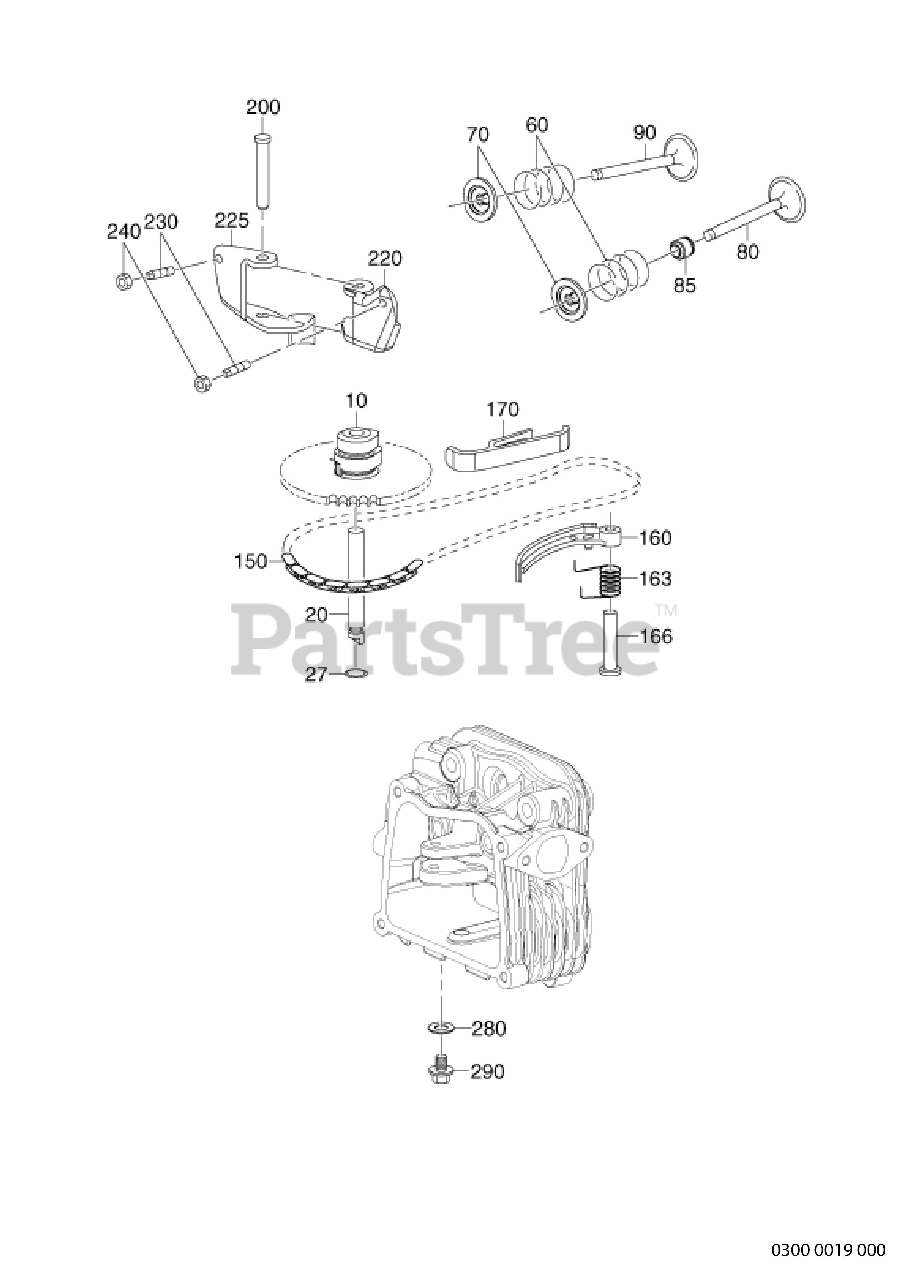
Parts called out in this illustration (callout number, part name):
70	SPRING RETAINER
150	CHAIN - 88 LINK
163	TENSIONER SPRING
166	TENSIONER SHAFT
200	ROCKER ARM PIVOT
220	INLET ROCKER ARM
225	EXHAUST ROCKER ARM
230	VALVE C/L ADJ STUD
240	VALVE C/L ADJ NUT
290	BOLT
